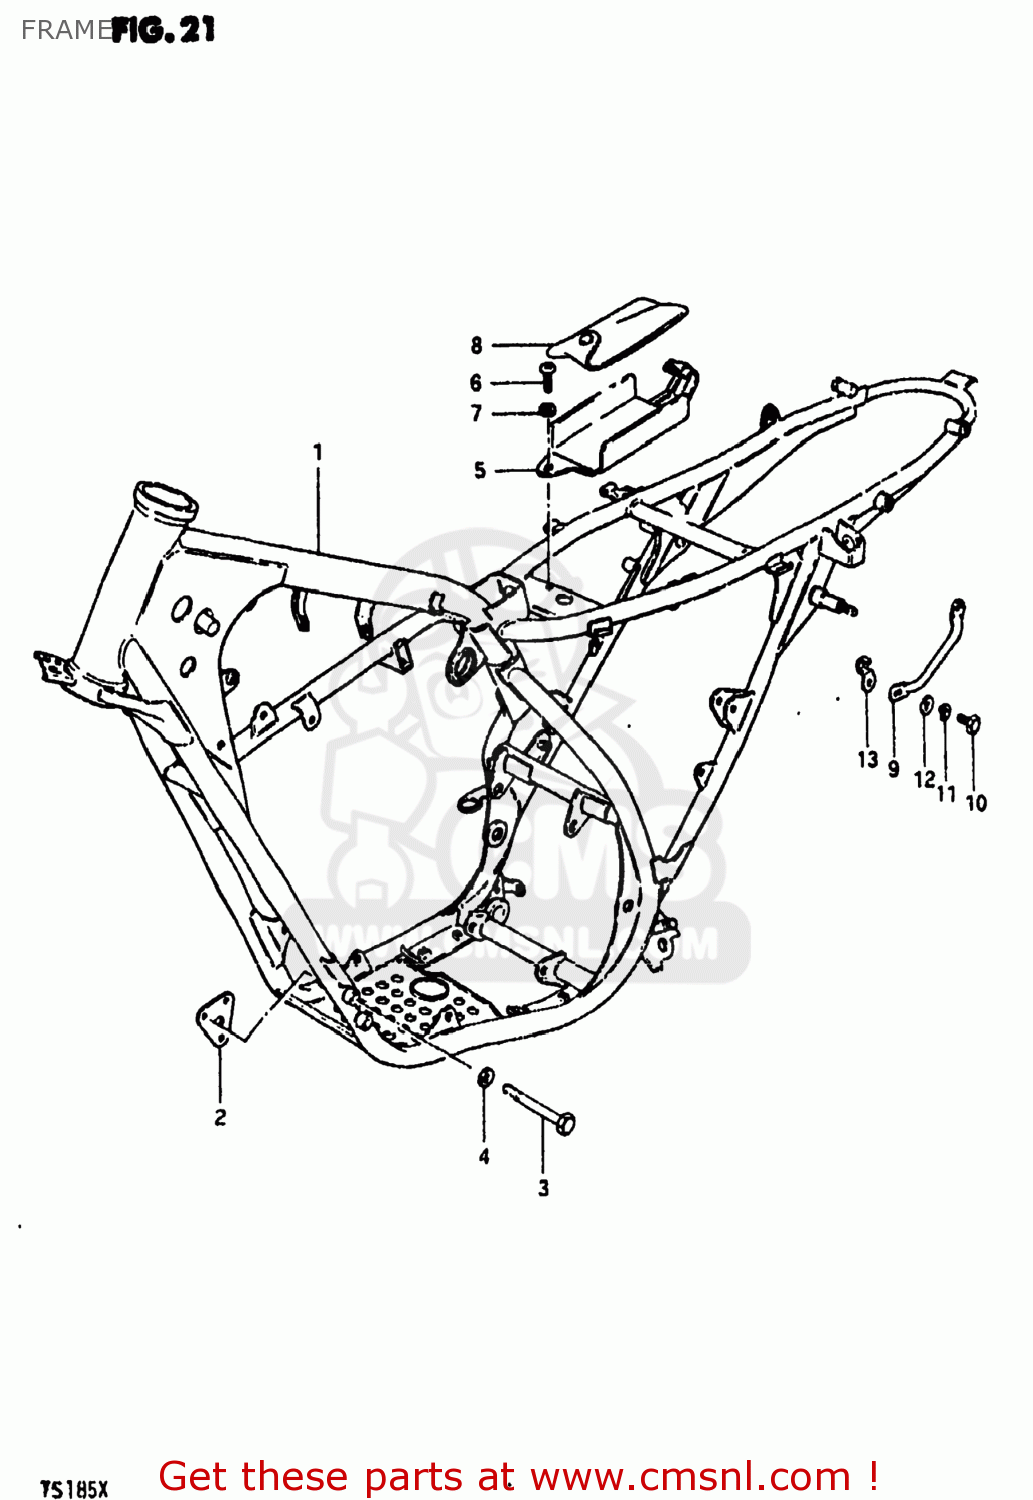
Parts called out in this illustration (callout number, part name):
1	FRAME
2	PLATE,ENG MTG,L
3	BOLT 8X55
4	WASHER
5	HOLDER,TOOL
6	SCREW
7	WASHER
8	TOOL SET
9	GRIP,FRAME HANDLE
10	BOLT
11	LOCK WASHER
12	WASHER
13	HOOK,HELMET HOLDER
